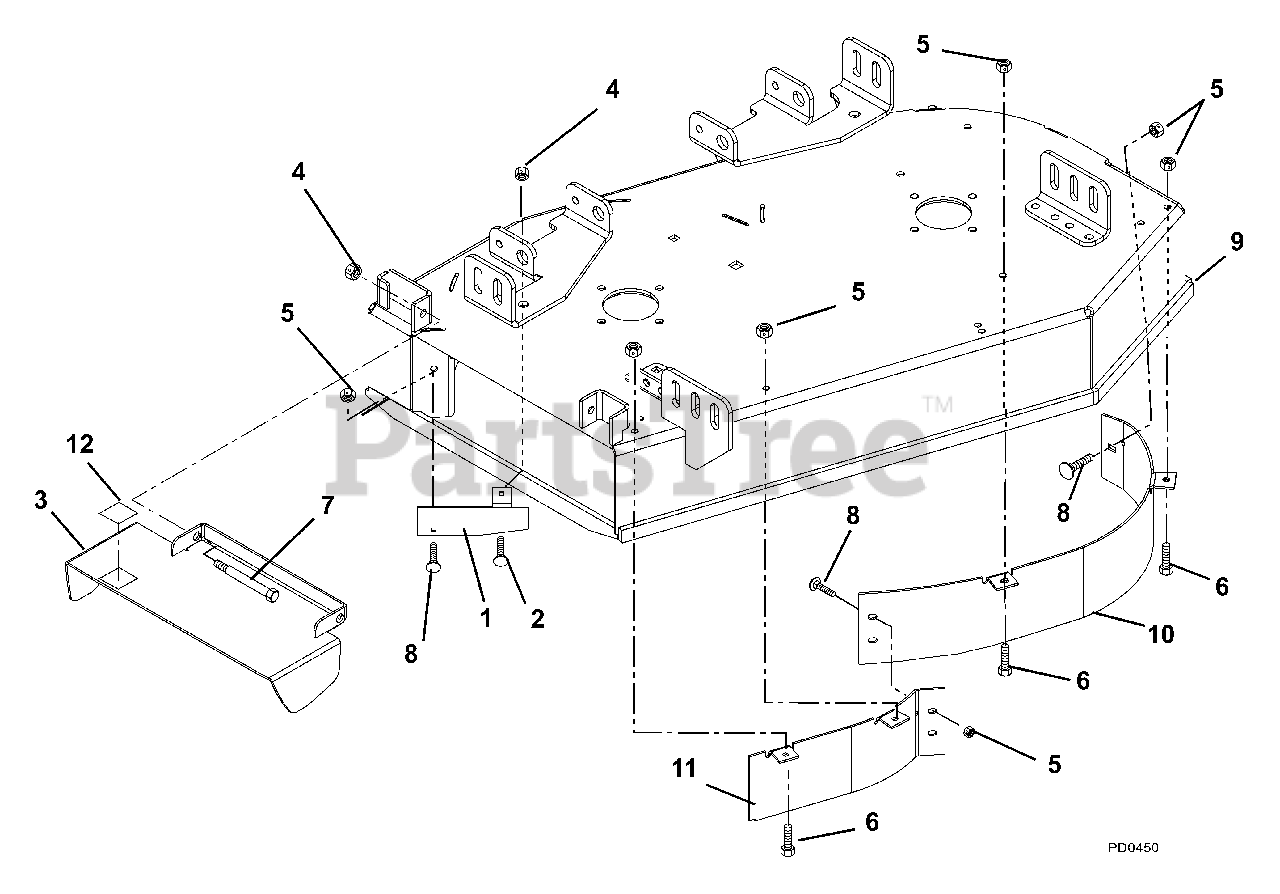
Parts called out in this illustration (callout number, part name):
1	Baffle, Deflector
2	Bolt, Round Head Square Neck .38-16 x 1.25 Grade 5
3	Chute, Discharge
4	Nut, Nyloc Flange 3/8-16
5	Nut, Nyloc Flange 5/8-18
6	Bolt-Hex .31-18 x .75 Grade 5
7	Bolt-Shoulder .38-16 x .50 Socket Head
8	Bolt-Round Head Square Neck .31-18 x .75 Grade 5
9	Weldment, 34" Deck
10	Baffle, 34" Front Left Hand
11	Baffle, 34" Front Right Hand
12	Grip, Pedal 1.50 x 3.00
